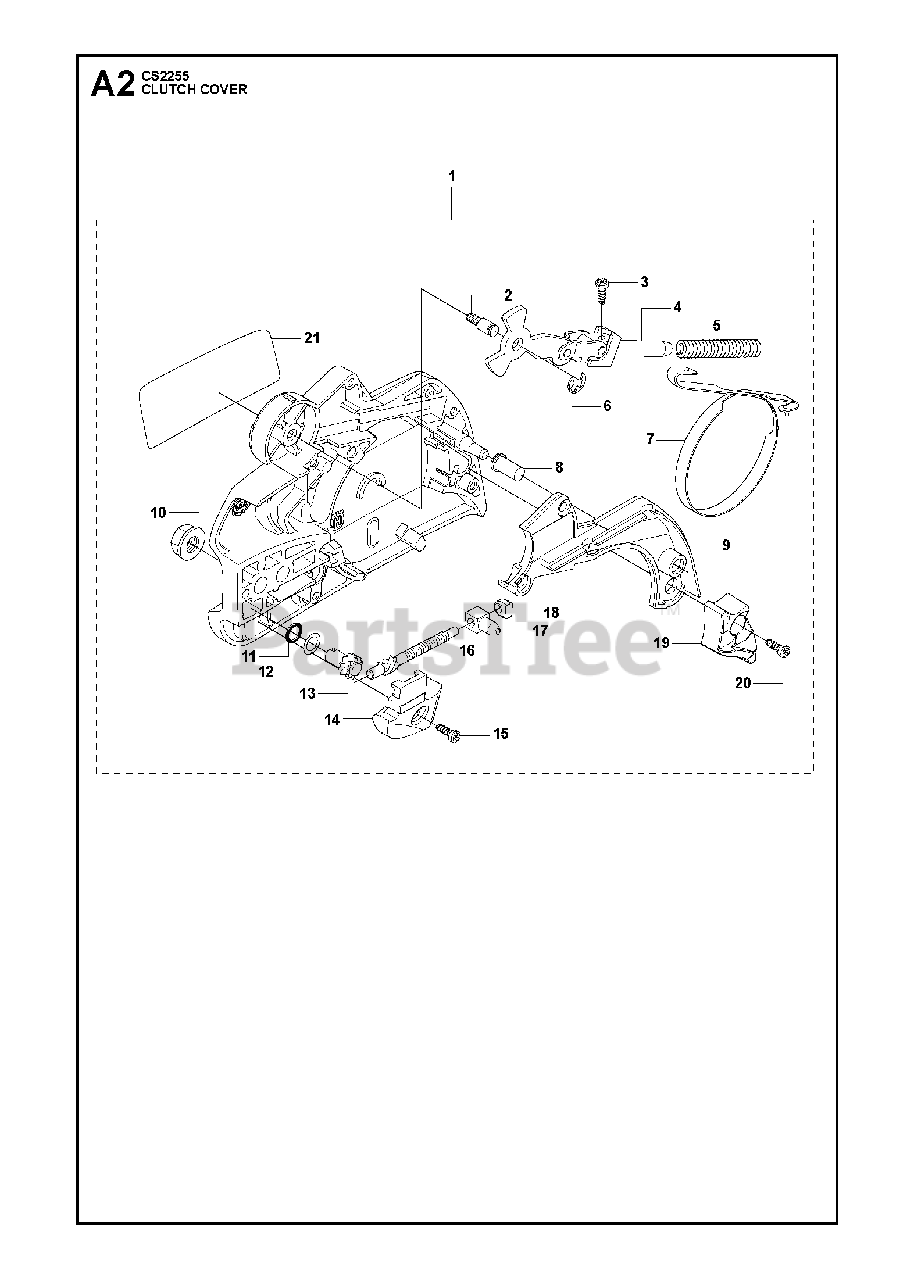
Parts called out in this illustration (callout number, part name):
1	CLUTCH COVER ASSY
2	PIN
3	SCREW
4	JOINT
5	SPRING
6	E-RING 4
7	BRAKE BAND
8	SLEEVE
9	COVER, CHAIN BRAKE
10	NUT M8 FLANGE
11	O-RING
12	WASHER
13	SCREW
14	CHAIN GUIDE
15	SCREW
16	SCREW
17	PAWL
18	SLEEVE
19	WEAR GUARD, CHAIN
20	SCREW
